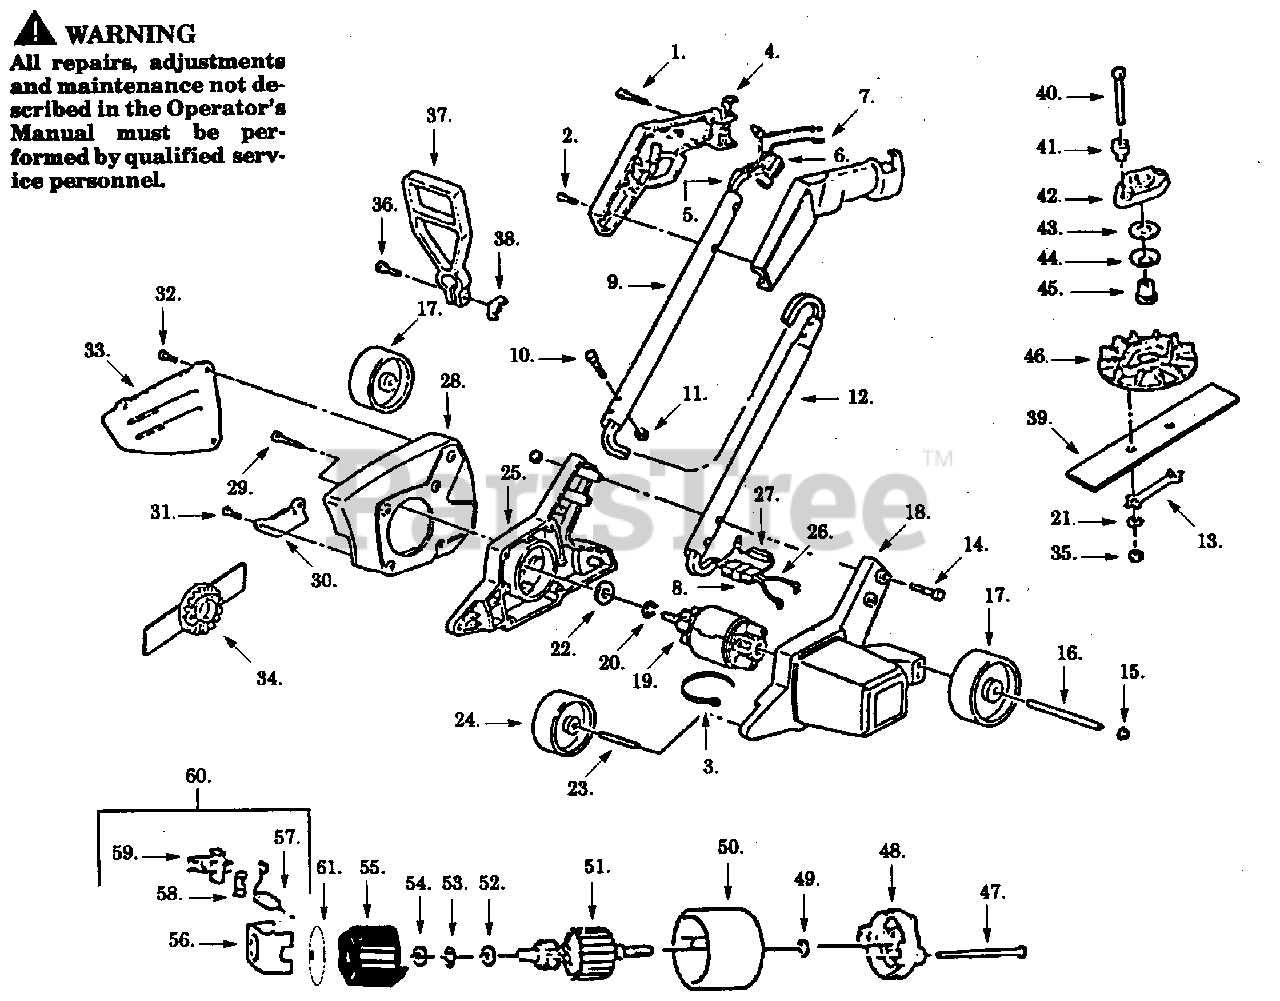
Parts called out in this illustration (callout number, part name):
3	Tie Strap
4	Model 970
4	Model 9075
5	Harness Ass'y.
6	Trigger Switch
7	Power Plug
9	Upper Tube
12	Lower Tube
13	Lock Strap
16	Rear Axle
17	Rear Wheel
18	Motor Cover
19	Motor Ass'y.
20	Retaining Ring
21	Lockwasher
23	Front Axle
24	Front Wheel
26	P.C. Board Ass'y.
27	Resister
28	Housing Guard
30	Blade Guide
33	Blade Guard
34	Blade Ass'y.
37	Assist Handle
38	Wing Nut
41	Insulating Sleeve
42	Clutch Plate
44	Spring Washer
45	Clutch Sleeve
48	Endbell Ass'y. (Drive)
50	Field Ass'y.
51	Armature Ass'y.
54	Retaining Ring
55	Endbell Ass'y. (Brush)
56	Insulator
57	Carbon Brush
58	Spring Brush
59	Brush Holder
60	Brush Kit
61	Brush Insulator
